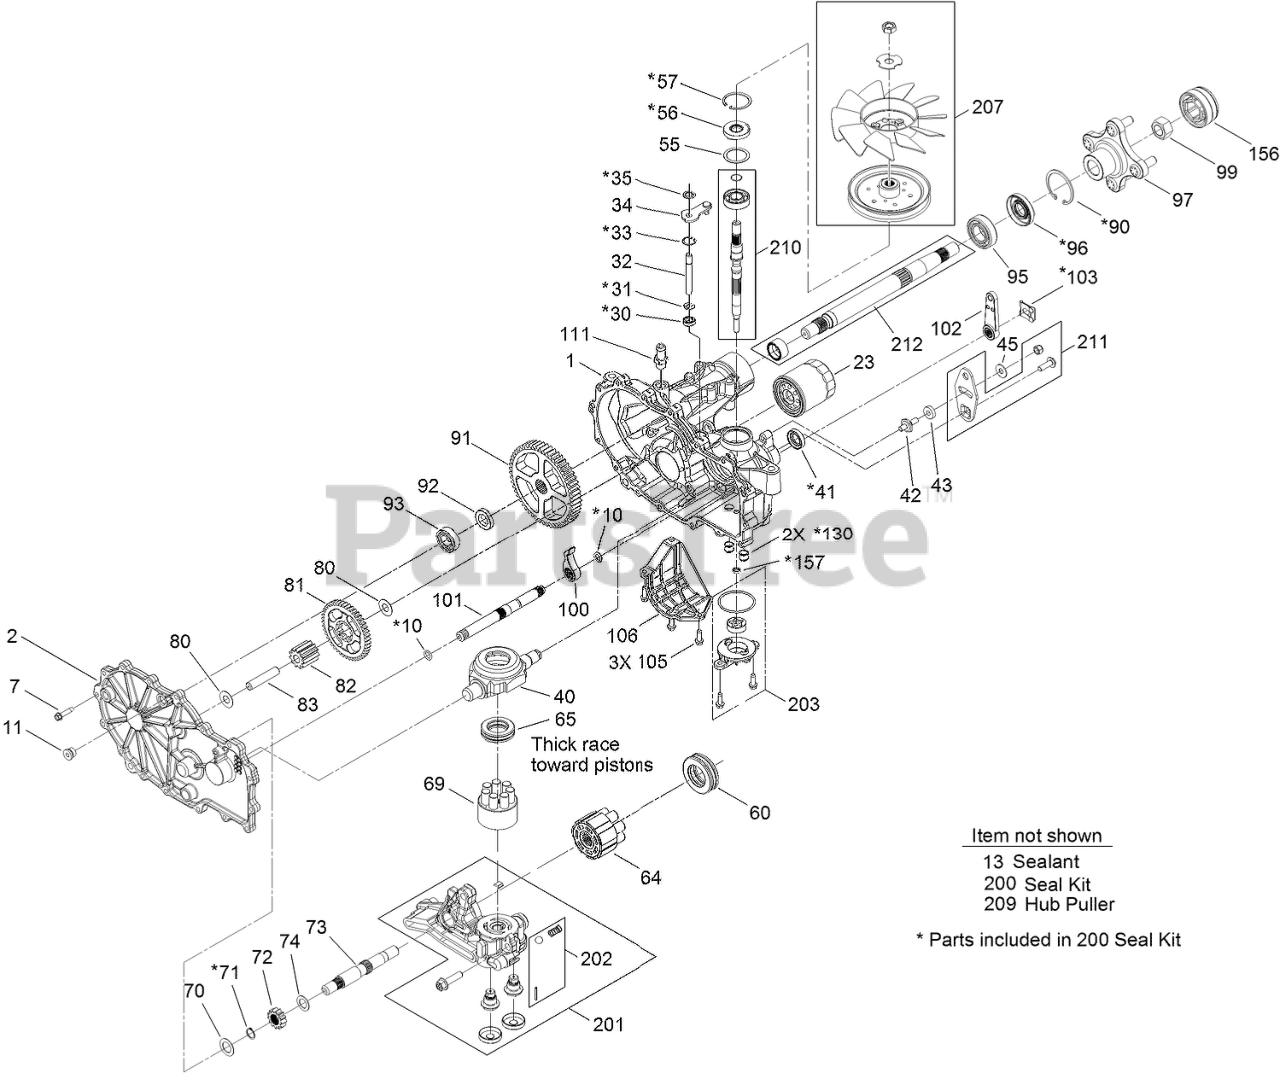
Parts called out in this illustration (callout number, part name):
1	LH MAIN HOUSING KIT
2	LH SIDE COVER KIT
7	SCREW-HHF
10	O-RING
11	PLUG-THREAD, STRAIGHT
23	ELEMENT-OIL FILTER, HYD
30	SEAL-LIP
31	RING-RETAINING, EXTERNAL
32	ROD-BYPASS
33	RING-RETAINING, INTERNAL
34	ARM-BYPASS
35	RING-RETAINING, EXTERNAL
40	SWASHPLATE-TRUNNION
41	SEAL-LIP
43	PUCK-FRICTION
45	WASHER-PIVOT
55	SPACER
56	SEAL-LIP
57	RING-RETAINING
60	BEARING-THRUST
64	MOTOR CYLINDER BLOCK KIT
65	BEARING-THRUST
69	PUMP BLOCK ASM
70	WASHER-FLAT
71	RING-RETAINING
72	GEAR-13T
73	SHAFT-MOTOR
74	WASHER
80	WASHER
81	GEAR-46T
82	GEAR-11T
83	PIN-JACKSHAFT
90	RING-RETAINING
91	GEAR-54T
92	SPACER
93	BEARING-BALL
95	BEARING-BALL
97	HUB KIT
99	NUT
100	PAWL-BRAKE
101	BRAKE SHAFT KIT
102	HANDLE-BRAKE
103	CLIP-RETAINING
106	GUARD-FILTER, LH
111	ADAPTER-STRAIGHT
130	TUBE-CONNECTING
156	COVER-NUT, AXLE
157	SEAL-LIP
201	LH CENTER SECTION CHARGE KIT
202	CHARGE RELIEF KIT
203	CHARGE KIT
207	FAN AND PULLEY KIT
210	INPUT SHAFT KIT
211	CONTROL ARM KIT
212	AXLE SHAFT KIT
